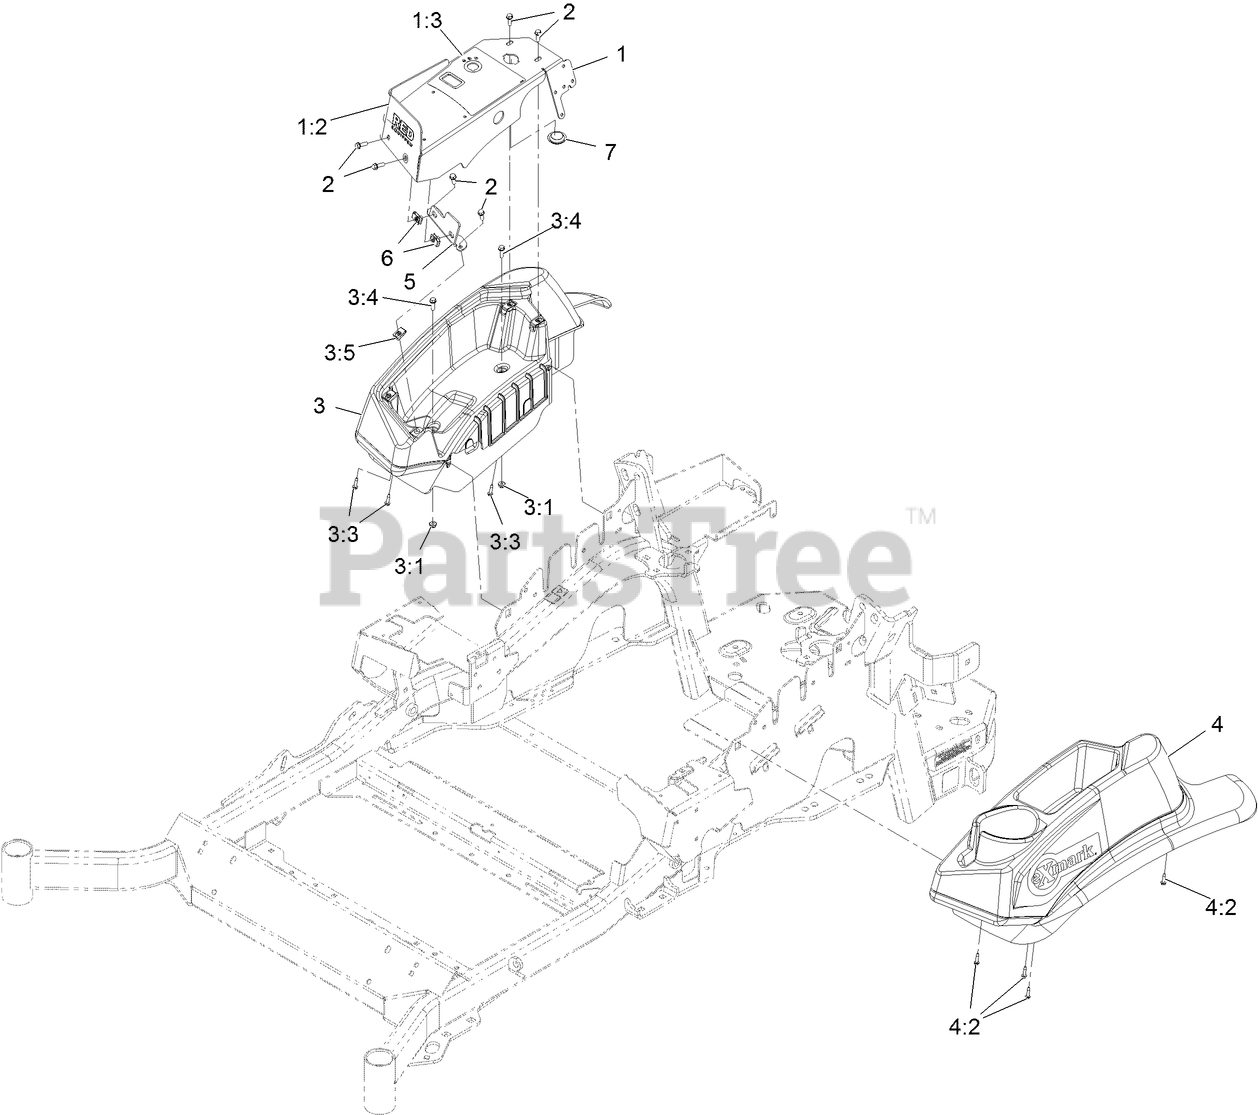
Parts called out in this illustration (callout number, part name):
1	COVER PANEL ASM W/DECALS
1:2	DECAL-CONTROL PANEL RED
1:3	DECAL-CONSOLE
2	SCREW-HWH
3	CONSOLE,RH NARROW ASM
3:3	SCREW,THD FORM,HWH
3:4	SCREW-HWH
4	CONSOLE.LH NARROW ASM
4:2	SCREW,THD FORM,HWH
5	BRACKET-CONSOLE
7	PLUG-PLASTIC
